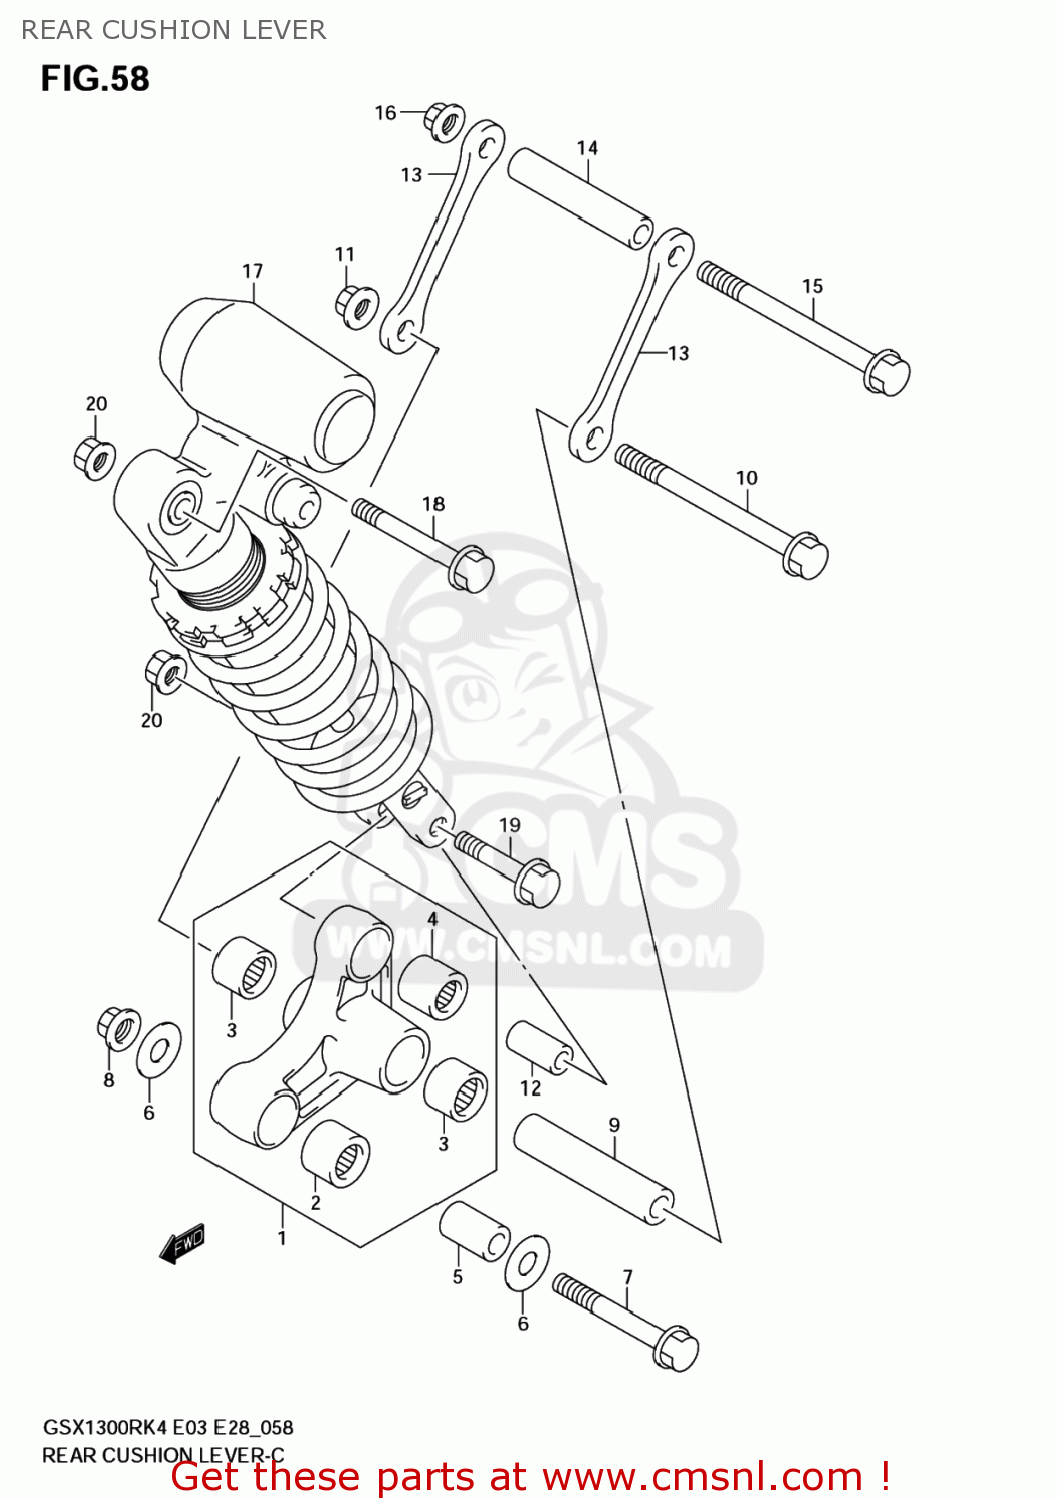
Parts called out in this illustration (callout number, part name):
1	LEVER SET,RR CUSHION
2	BEARING(20X27X30)
3	BEARING(20X27X23.5)
4	BEARING(17X24X26)
5	SPACER,RR CUSHION LEVER FR
6	WASHER
7	BOLT,RR CUSHION LEVER FR
8	NUT
9	SPACER,RR CUSHION LEVER CTR
10	BOLT,RR CUSHION LEVER CTR
11	NUT
12	SPACER,RR CUSHION LEVER
13	ROD,RR CUSHION
14	SPACER,RR CUSHION LEVER CTR
15	BOLT,RR CUSHION LEVER CTR
16	NUT
17	ABSORBER ASSY,RR SHOCK
18	BOLT(10X70)
19	BOLT(10X58)
20	NUT
